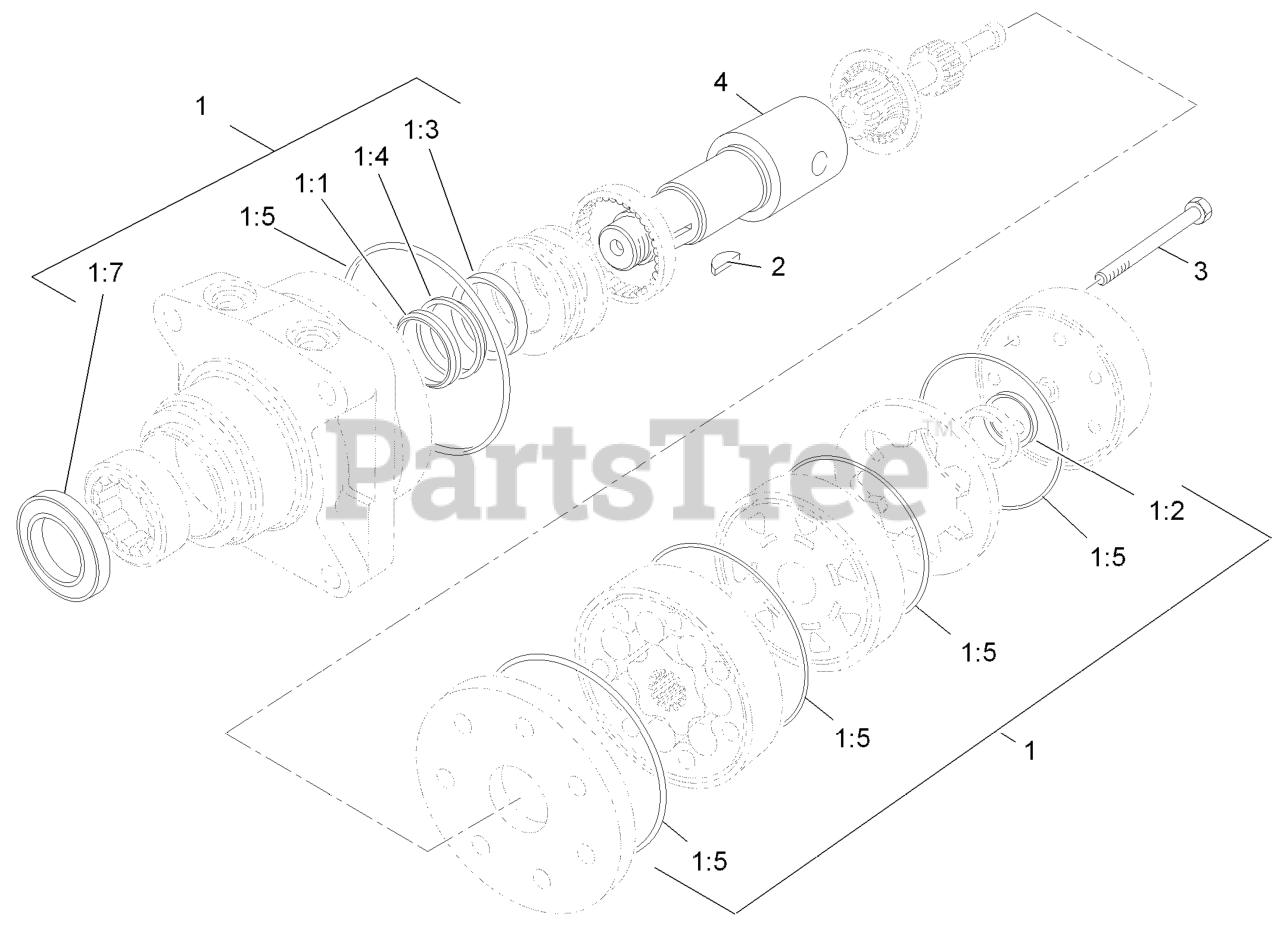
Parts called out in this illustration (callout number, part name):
1	SEAL KIT
1:1	Ring-Back Up
1:2	Seal-Commutator
1:3	Seal-Shaft (Viton)
1:4	Washer-Back Up, Steel
1:5	Ring-Seal (Viton)
1:7	Seal-Dirt And Water
2	KEY-WOODRUFF
3	BOLT-SPECIAL
4	SHAFT-COUPLING
